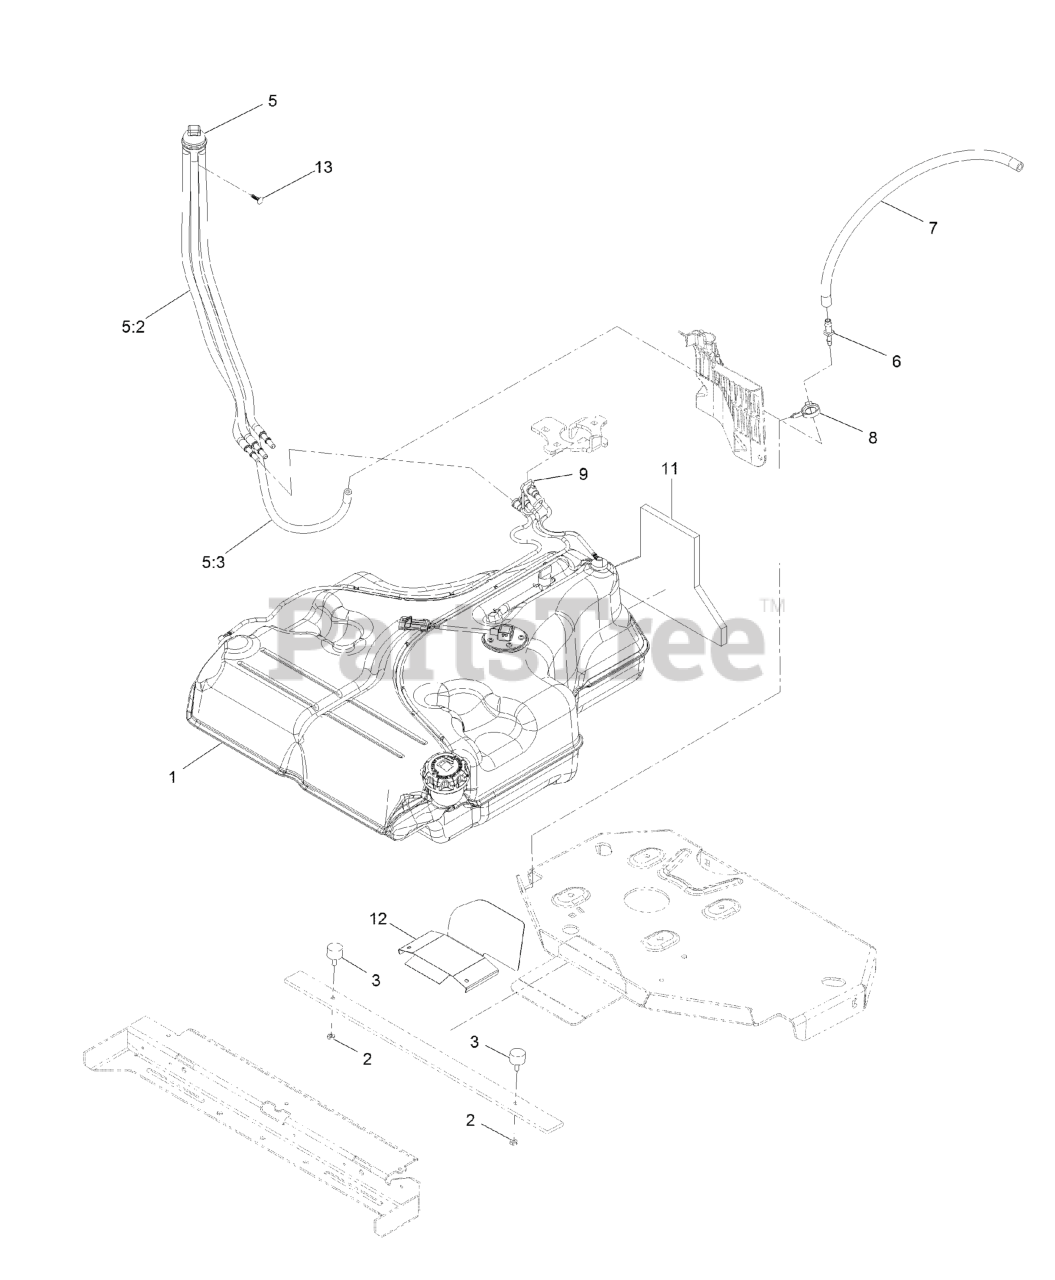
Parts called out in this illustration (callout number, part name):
1	FUEL TANK ASM
2	NUT-JAM
5	FUEL MANIFOLD VENT ASM
5:2	HOSE-FUEL
5:3	HOSE-FUEL
6	FITTING-STRAIGHT
7	HOSE-FUEL
8	CLAMP-HOSE
9	RETAINER-LINE, VAPOR
11	INSULATION-FOAM, FUEL TANK
12	GUARD-EXHAUST
13	PLUG-PLASTIC
